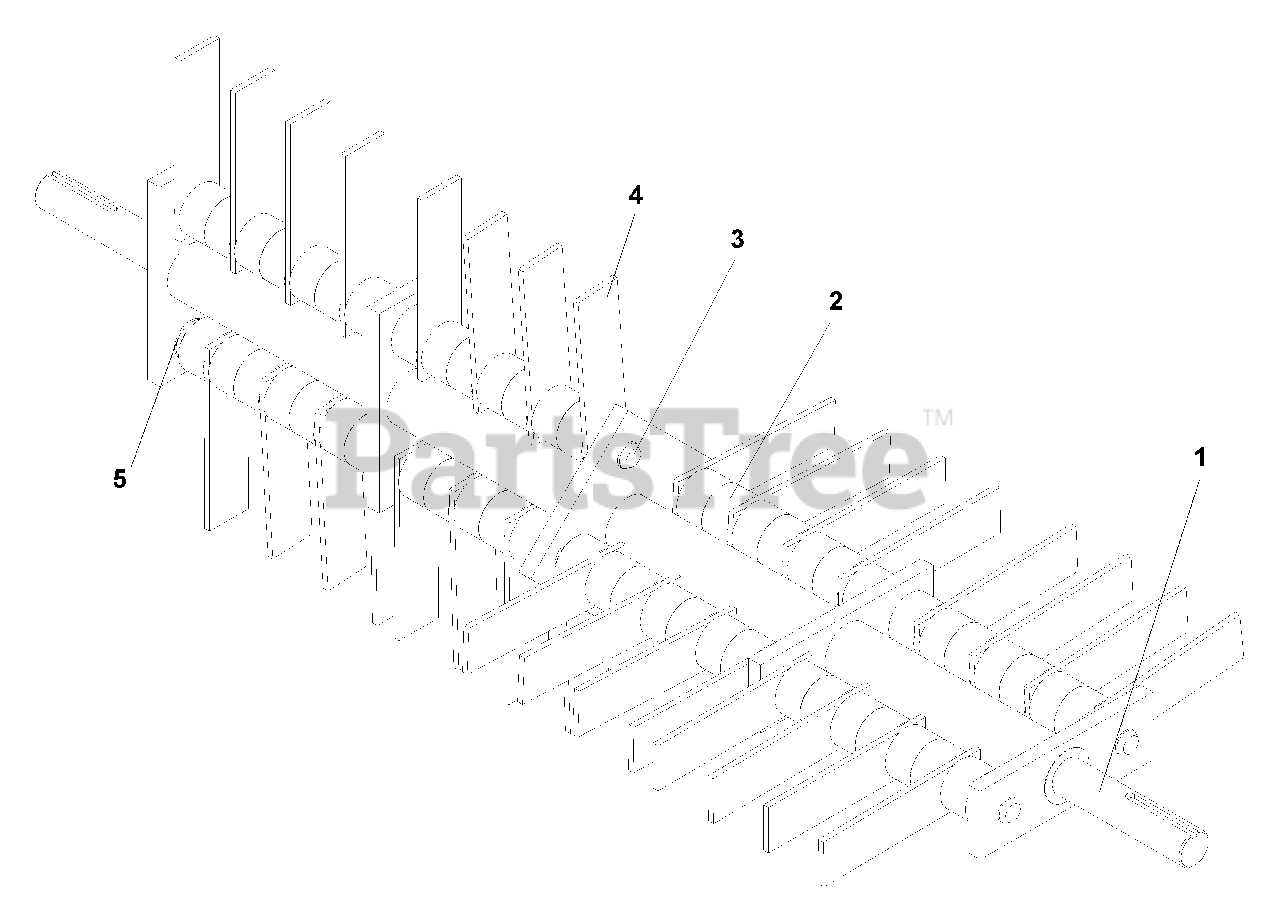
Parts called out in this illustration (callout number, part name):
2	SPACER SET (56 SPACERS)
3	SHAFT & HARDWARE SET (4 SHAFTS)
4	BLADE SET (32 BLADES)
4	BLADES W/SHAFTS & HARDWARE SET (32 BLADES)
5	E-RING 1/2
